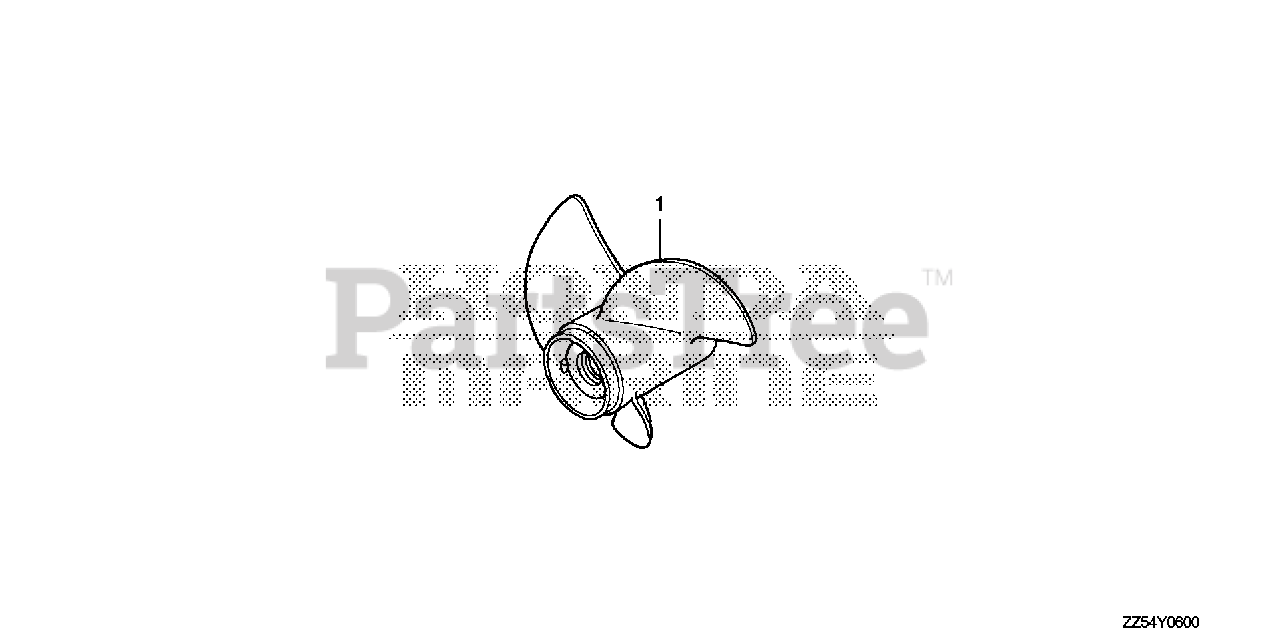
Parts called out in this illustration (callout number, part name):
1	PROPELLER, THREE-BLADE (11-3/8X12) *NH283* (STIN GRAY)
1	PROPELLER, THREE-BLADE (12-1/8X9) *NH283* (STIN GRAY)
1	PROPELLER, THREE-BLADE (11-5/8X11) *NH283* (STIN GRAY)
1	PROPELLER, THREE-BLADE (11-1/8X13) *NH283* (STIN GRAY)
1	PROPELLER, THREE-BLADE (11-1/8X14) *NH283* (STIN GRAY)
1	PROPELLER, THREE-BLADE (11X15) *NH283* (STIN GRAY)
1	PROPELLER, THREE-BLADE (11-1/4X13) *NH283* (STIN GRAY)
1	PROPELLER, THREE-BLADE (11-1/2X12) *NH283* (STIN GRAY)
1	PROPELLER, THREE-BLADE (11-3/4X10) *NH283* (STIN GRAY)
1	PROPELLER, THREE-BLADE (11-1/2X14-1/4) *NH283* (STIN GRAY)
